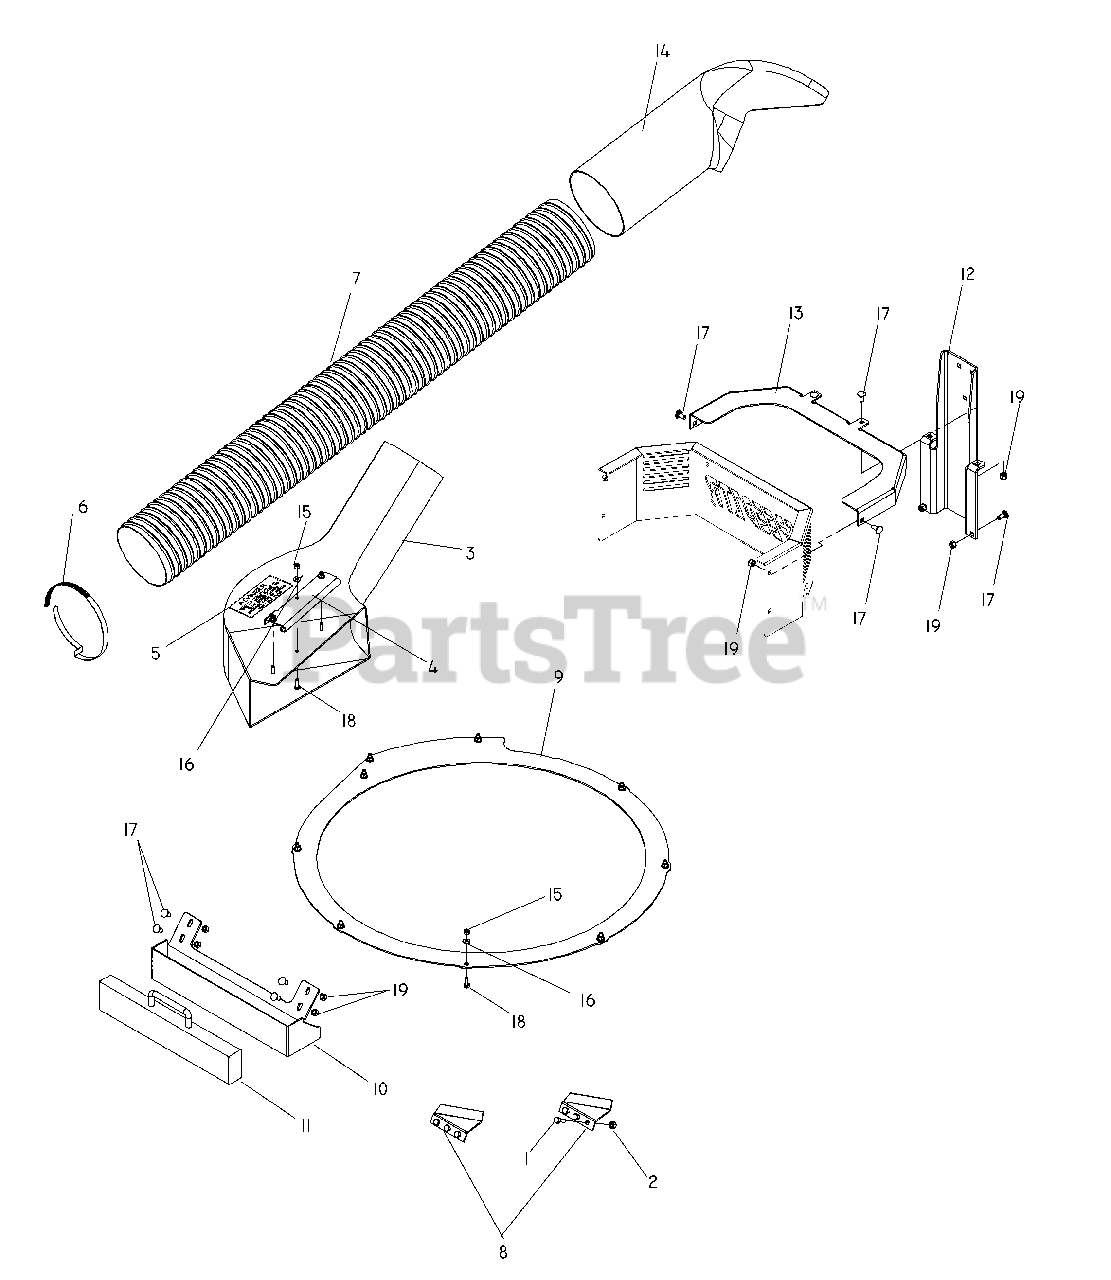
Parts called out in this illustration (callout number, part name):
1	HCS 5/16-24 X 7/8 GR 5 ZD
2	NUT 5/16F NYLOC
3	DISCHARGE ADAPTER W/DECAL
4	DISCHARGE MT. BRACKET
5	G.C.WARNING DECAL
6	HOSE CLAMP
7	FLEX HOSE 6 X 50
8	HI LIFT ADAPTOR
9	BOOSTER RING
10	WEIGHT BOX WLDT.
11	WEIGHT WLDT. RAM
12	BRACKET, HANGER
13	REINFORCEMENT - PAINTED
14	UPPER CHUTE - MODIFIED
15	NUT 1/4-20 NYLOC
16	WASHER 1/4 SAE
17	BOLT 5/16C X 3/4" CARRIAGE
18	HCS 1/4C X 3/4 HCS
19	NUT 5/16 NYLOC
